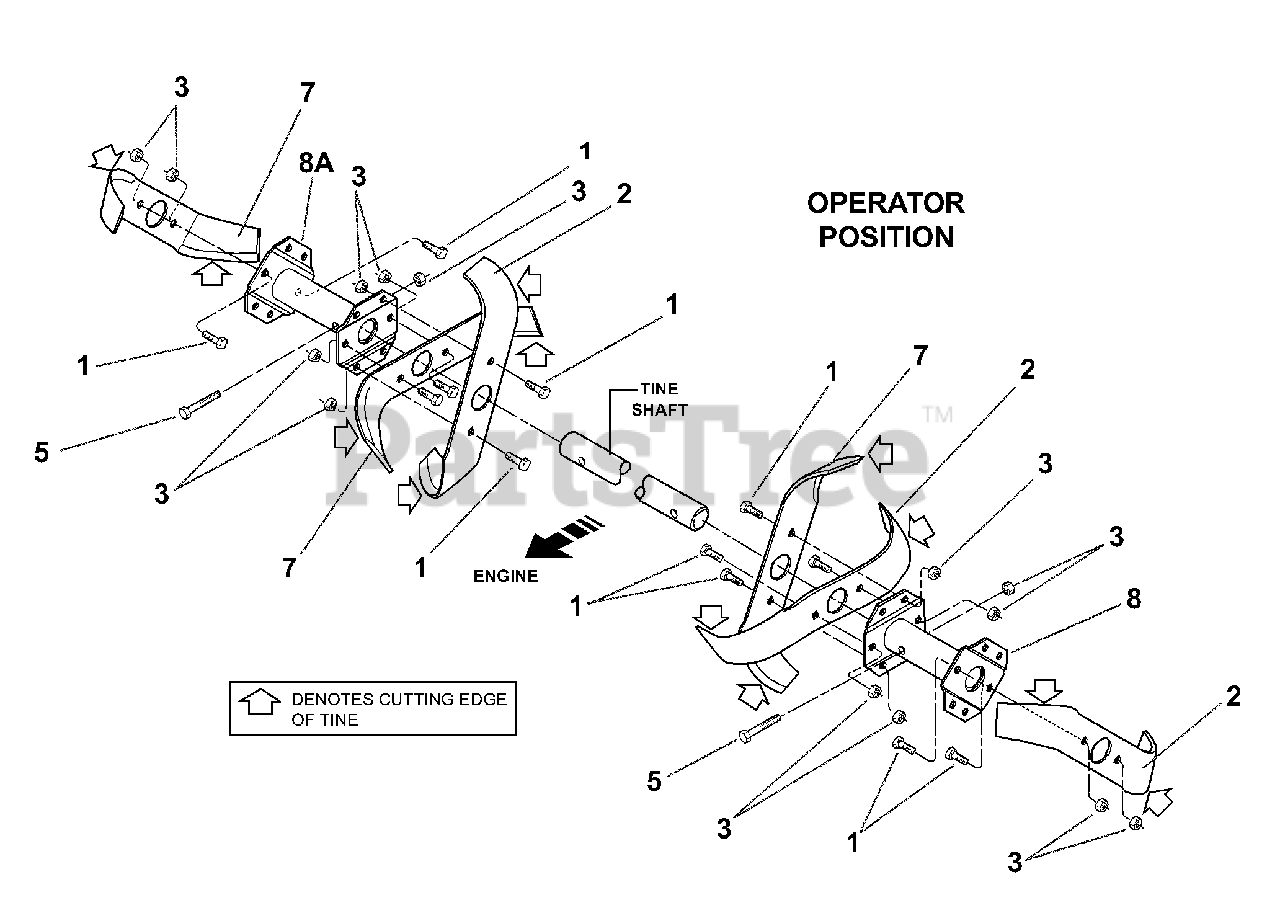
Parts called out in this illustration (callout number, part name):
1	Hex Hd. Screw, 3/8-16 x 3/4
2	Tine - right-hand
3	Hex Lock Nut, 3/8-16
5	Hex Hd. Screw, 3/8-16 x 2, Grade 8
7	Tine - left-hand
8	Tine Holder, left-side
8A	Tine Holder, right-side
